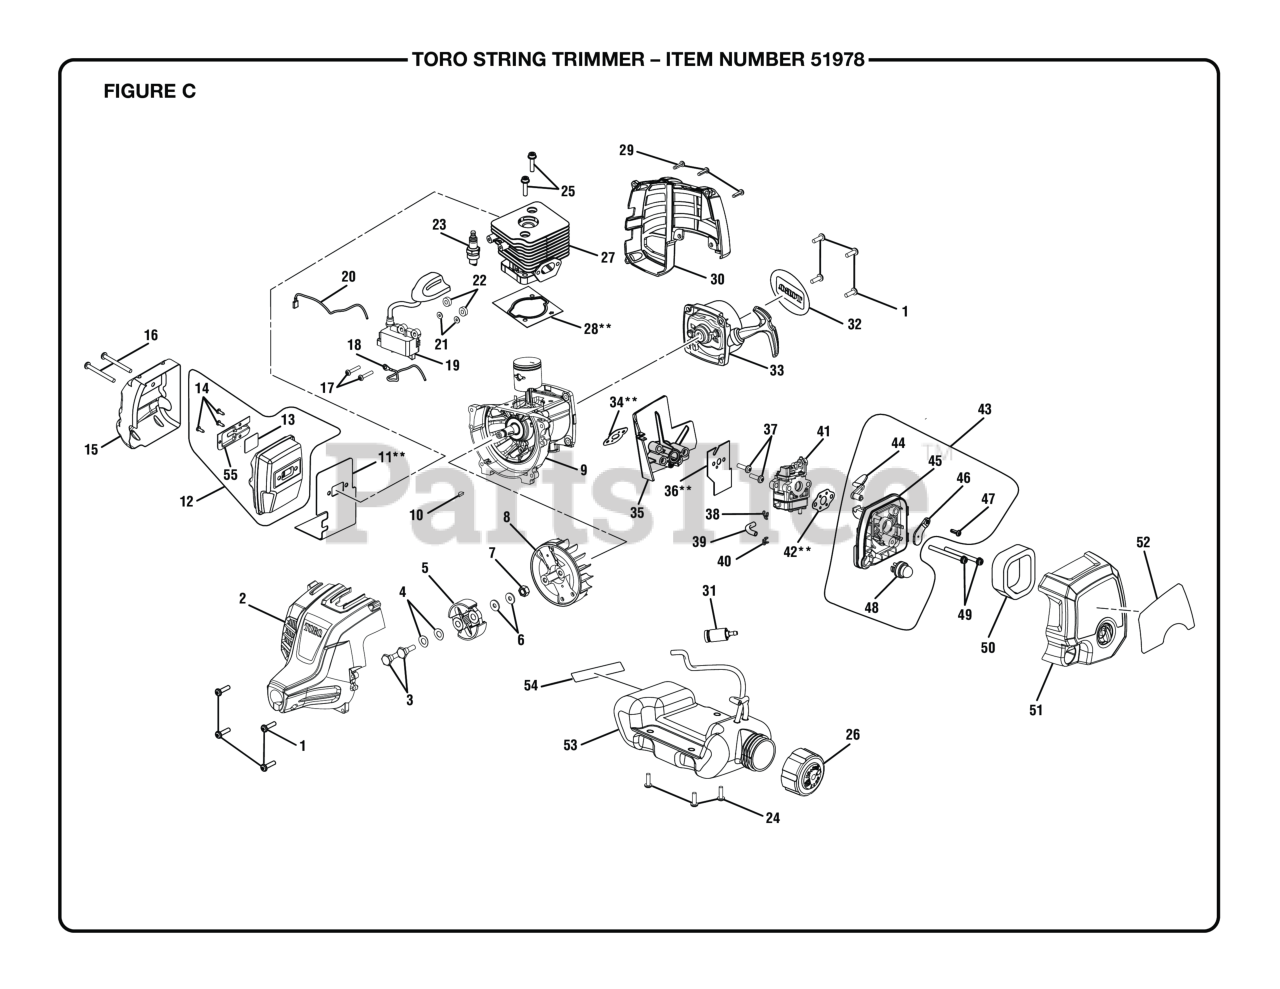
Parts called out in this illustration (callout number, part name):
1	Cap Screw w/Washer (M5 x 16 mm, T25 Torx Soc. Hd.)
2	Front Housing Assembly
3	Clutch Shoulder Bolt (M6 x 22.5 mm, Hex Hd.)
4	Washer (Curved)
5	Clutch Assembly
6	Washer (ID6 x OD15 x 1.2t)
7	Flange Nut (M8, Flywheel)
9	Crankcase Assembly.
10	WOODRUFF KEY (10 mm X 3 mm)
11	Muffler Gasket
12	Muffler Assembly (Inc. Key Nos. 3-4)
13	SCREEN
14	Screw (6-20 x 1/4 in., T20 Torx Pan Hd. S.T.)
15	HEAT SHIELD
16	Screw (M5 x 50 mm, Torx Slotted Recessed Pan Hd.)
17	Screw (M4 x 22 mm, T20 Torx Slotted Recessed Pan Hd.)
18	Lead Wire Assembly, Red
19	Coil Boot Assembly
20	Lead Wire Assembly, Black
21	Flat Washer (OD10 x ID42 x 1t)
22	Phenolic Spacer (Ignition Module)
23	SPARK PLUG (CHAMPION RCJ4)
24	Shoulder Screw w/Washer (M4 x 14 mm, T25 Torx Truss Hd.)
25	Screw (M5 x 22 mm, T25 Torx Soc. Hd.)
26	Fuel Cap Assembly
28	Gasket
29	Screw (M4 x 18 mm, T20 Torx Pan Hd. S.T.)
30	Rear Engine Housing
31	Fuel Filter
32	Logo Label (Rear)
33	Starter Recoil & Starter Cup Assembly
34	Heat Dam Insulator
36	Gasket
37	Screw w/Washers (M5 x 30 mm, T25 Torx Pan Hd.)
38	Clip-hose (Id 4.9)
39	Fuel Line (45 mm)
40	CLIP-HOSE (ID 4.9)
41	CARBURETOR ASSEMBLY
42	Carburetor Gasket
43	Filter Housing Assembly
44	CHOKE LEVER
45	CARBURETOR PLATE
46	Screw (M4 x 12 mm, T20 Torx Pan Hd. S.T.)
47	Screw (M4 x 12 mm, Slotted Recessed Pan Hd.)
48	Primer Bulb Assembly
49	Screw (M5 x 44 mm,T25 Torx Hd. Carburetor)
50	Air Filter (Element)
51	Airbox Cover Assembly w/Label
52	Starting Instructions Label
53	Fuel Tank & Cap Assembly
54	Combustion Warning Label
55	Trimmer Outlet
